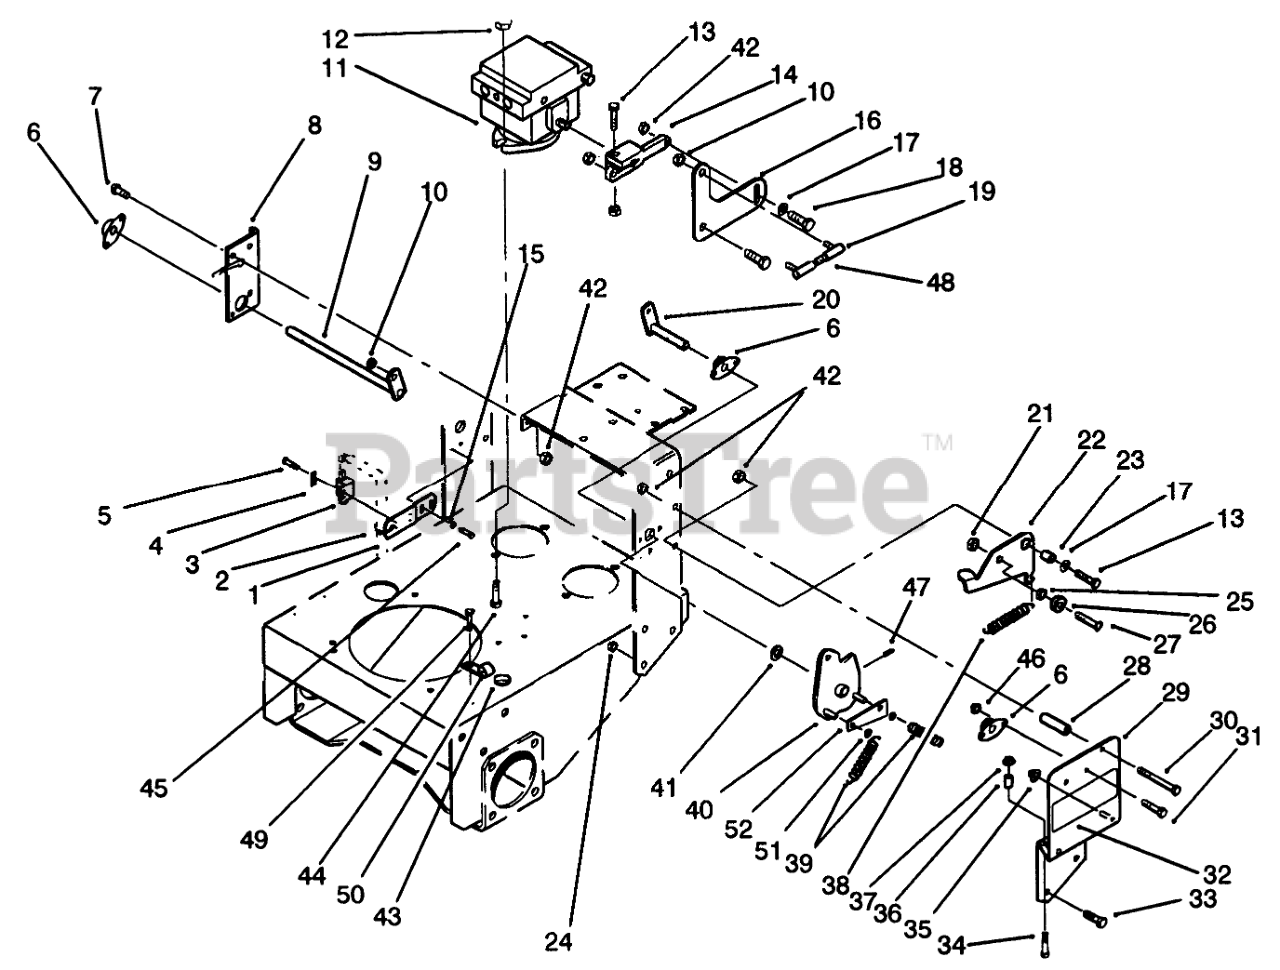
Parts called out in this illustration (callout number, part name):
1	NEUTRAL BRACKET B
2	TIE-CABLE
3	SWITCH-POLE, SINGLE
4	PLATE-SWITCH
5	SCREW-TAPTITE
6	SIDE FLANGE BEARING ASM
7	SCREW-HH
8	Bracket-Bushing
9	RH LEVER WA
10	NUT-LOCK, NI
11	HYDRAULIC PUMP
12	NUT-HF
13	SCREW-HH
14	ARM-PUMP
15	WASHER-FLAT
16	FOLLOWER ARM B
17	WASHER-PLAIN
18	SCREW-HH
19	JOINT-BALL
20	LH LEVER WA
21	NUT-LOCK, NI
22	Detent Arm Assembly L.H.
23	BUSHING-ARM, DETENT
24	NUT-LOCK, NI
25	SPACER-BEARING
26	BEARING-BALL
27	SCREW-HSBH
28	STOP-REVERSE
29	LEFT BRACKET WA R
30	SCREW-HH
31	SCREW-HH
32	DECAL-HYDRO
33	SCREW-HH
34	SCREW-HH
35	NUT-PUSH
36	SPACER-TUBULAR
37	NUT-LOCK, HHF
38	SPRING-DETENT
39	SPRING-EXTENSION
40	Pivot Assembly L.H.
41	WASHER-THRUST
42	NUT-LOCK, NI
43	GROMMET
44	SCREW-HH
45	Screw
46	NUT-LOCK, NI
47	PIN-ROLL, SLOTTED
48	BALL JOINT ROD
49	SCREW-HWH
50	CLAMP-R
51	NUT-PUSH IN
52	STOP BRACKET
